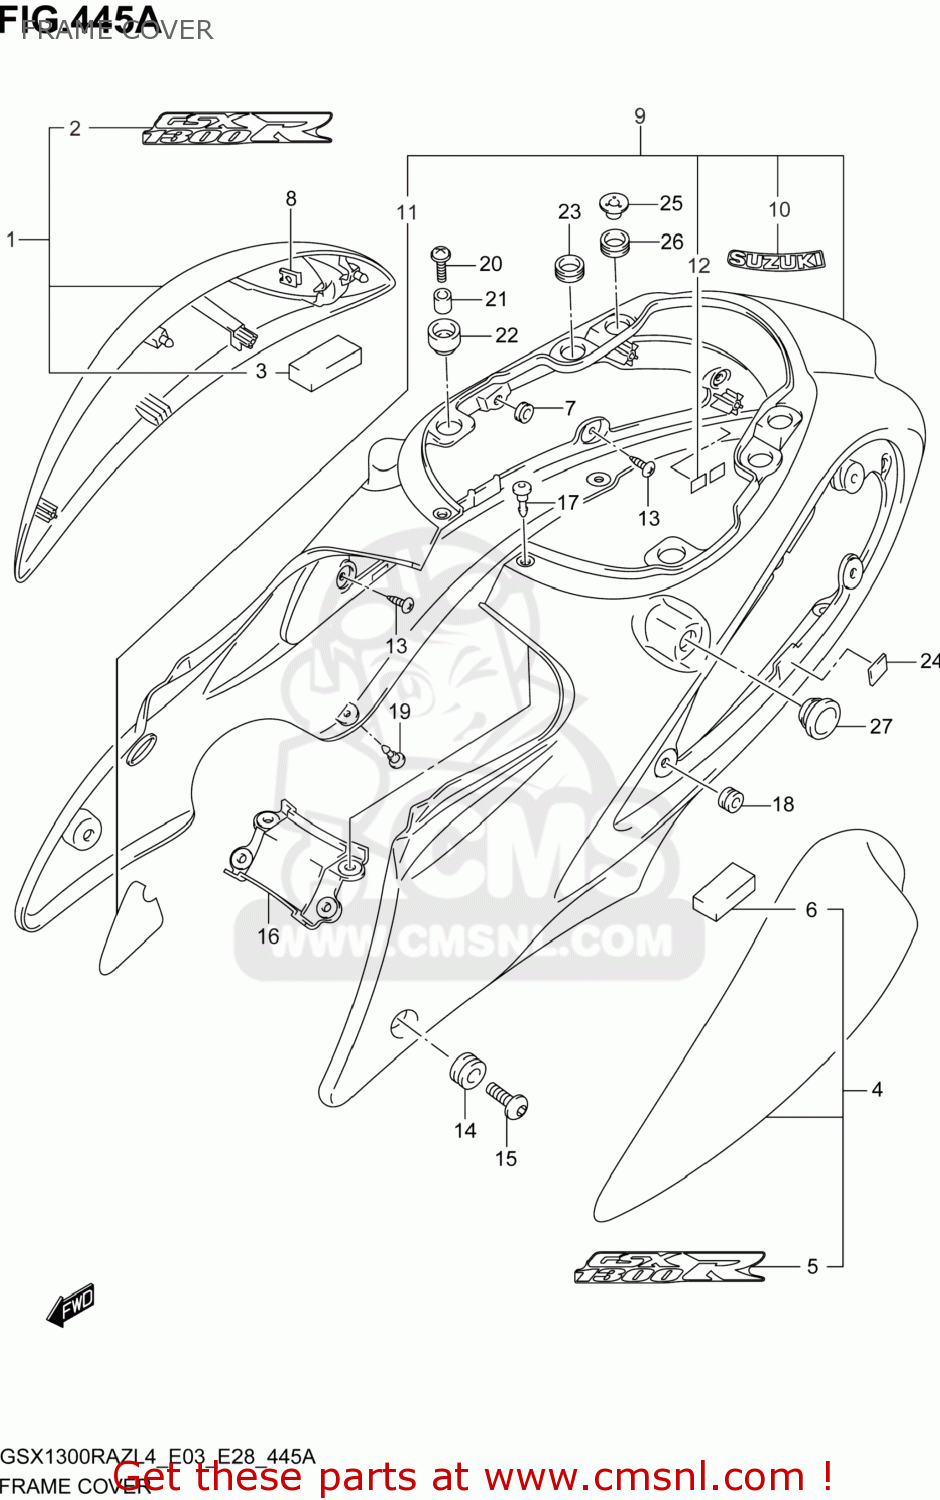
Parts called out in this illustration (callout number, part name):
1	COVER,FRAME,R(BLACK)
2	EMBLEM,FRAME COVER
3	CUSHION,FRAME COVER
4	COVER,FRAME,L(BLACK)
5	EMBLEM,FRAME COVER
6	CUSHION,FRAME COVER
7	CUSHION
8	NUT
9	COVER,FRAME CTR
10	EMBLEM(GRAY)
11	TAPE,CTR
12	CUSHION,SEAT TAIL COVER LWR RR
13	SCREW(5X15)
14	CUSHION
15	BOLT(6X20)
16	LID,FRAME COVER CTR
17	CLIP(BLACK)
18	CUSHION
19	CLIP
20	SCREW(6X20)
21	SPACER(6.5X10X11)
22	CUSHION,SEAT TAIL COVER CTR
23	CUSHION,FRAME COVER UPR RR
24	PROTECTOR(170X95X3.0)
25	WASHER,FRAME COVER
26	CUSHION,FRAME COVER UPR RR RR
27	CUSHION,FRAME COVER CTR
